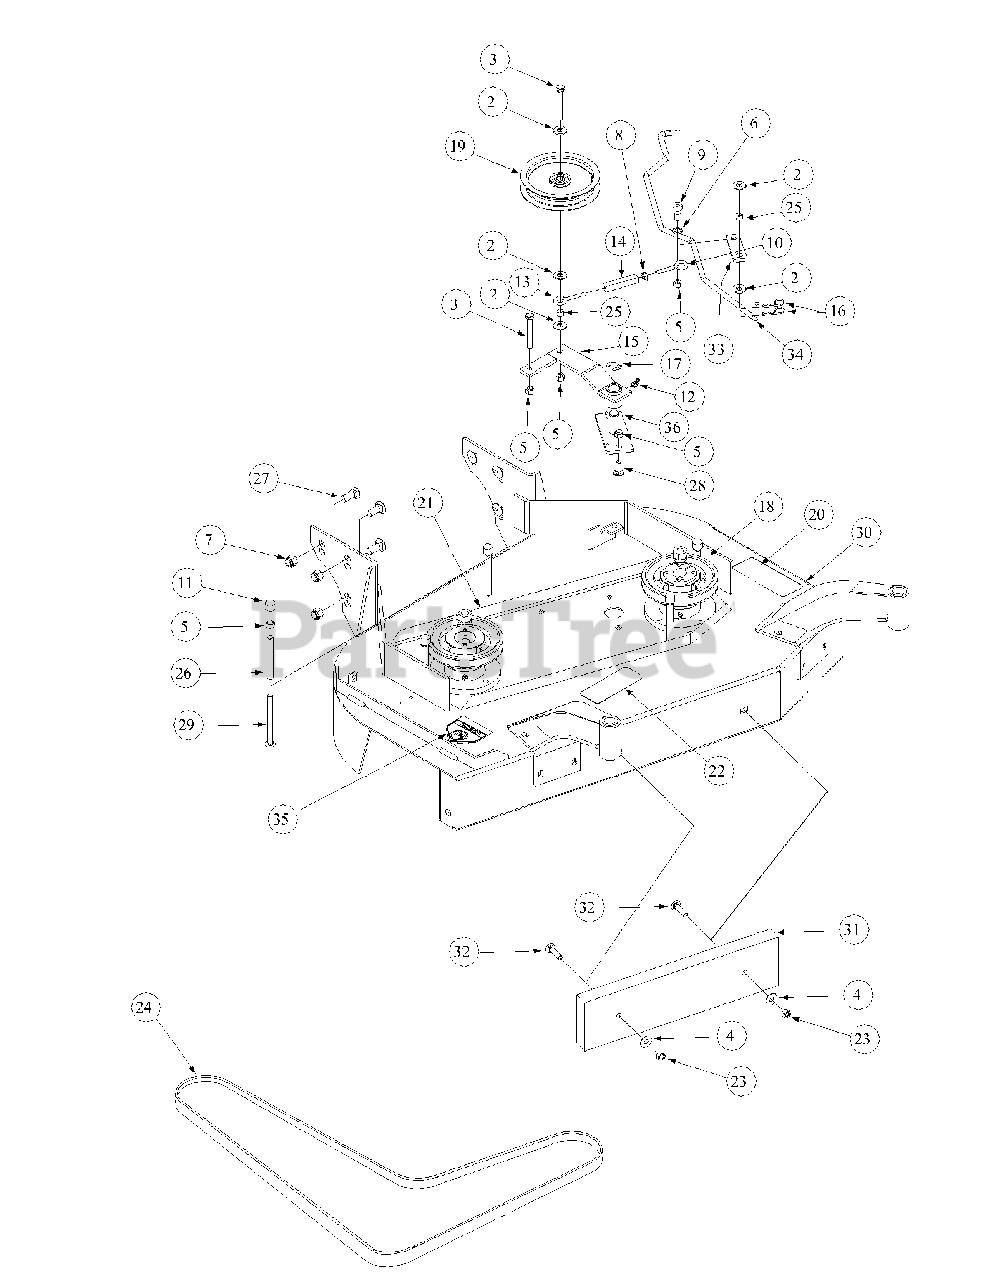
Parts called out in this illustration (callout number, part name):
2	Flat Washer, 3/8 Zinc
3	Hex Cap Screw, 3/8-16, 2.75
4	Flat Washer, 3/8 Zinc
5	Lock Nut, Nylon Insert, 3/8-16
6	Shim Washer
7	Lock Nut, Nylon Insert, 1/2-13
8	Hex Nut, 5/16-18
9	Shoulder Bol
10	Eye Bolt, Right Hand
11	Cap, Black Vinyl
12	Grease Fitting, 1/4-28 45°.
13	Eye Bolt, Left Hand
14	Turnbuckle
15	Idler Arm
16	Hair Pin, 3/8"-1/2"
17	E-Ring, Retainer
18	Pulley Deck
19	Idler Deck Take-up
20	Decal Rotating Blade
21	Deck Stiffener
22	Decal, Warning Shield Missing
23	Lock Nut, 3/8-16
24	Belt Drive
25	Turnbuckle, Sleeve
26	Spacer, Belt Guide
27	Carriage Bolt, 1/2-13 x 1-1/4
28	Carriage Bolt, 3/8-16 x 2
29	Carriage Bolt, 3/8-16 x 4.5
32	Carriage Bolt, 3/8-16 x 1-1/2
34	Rod Clutch Link
35	Decal, Danger Hands and Feet
36	Idler Base
